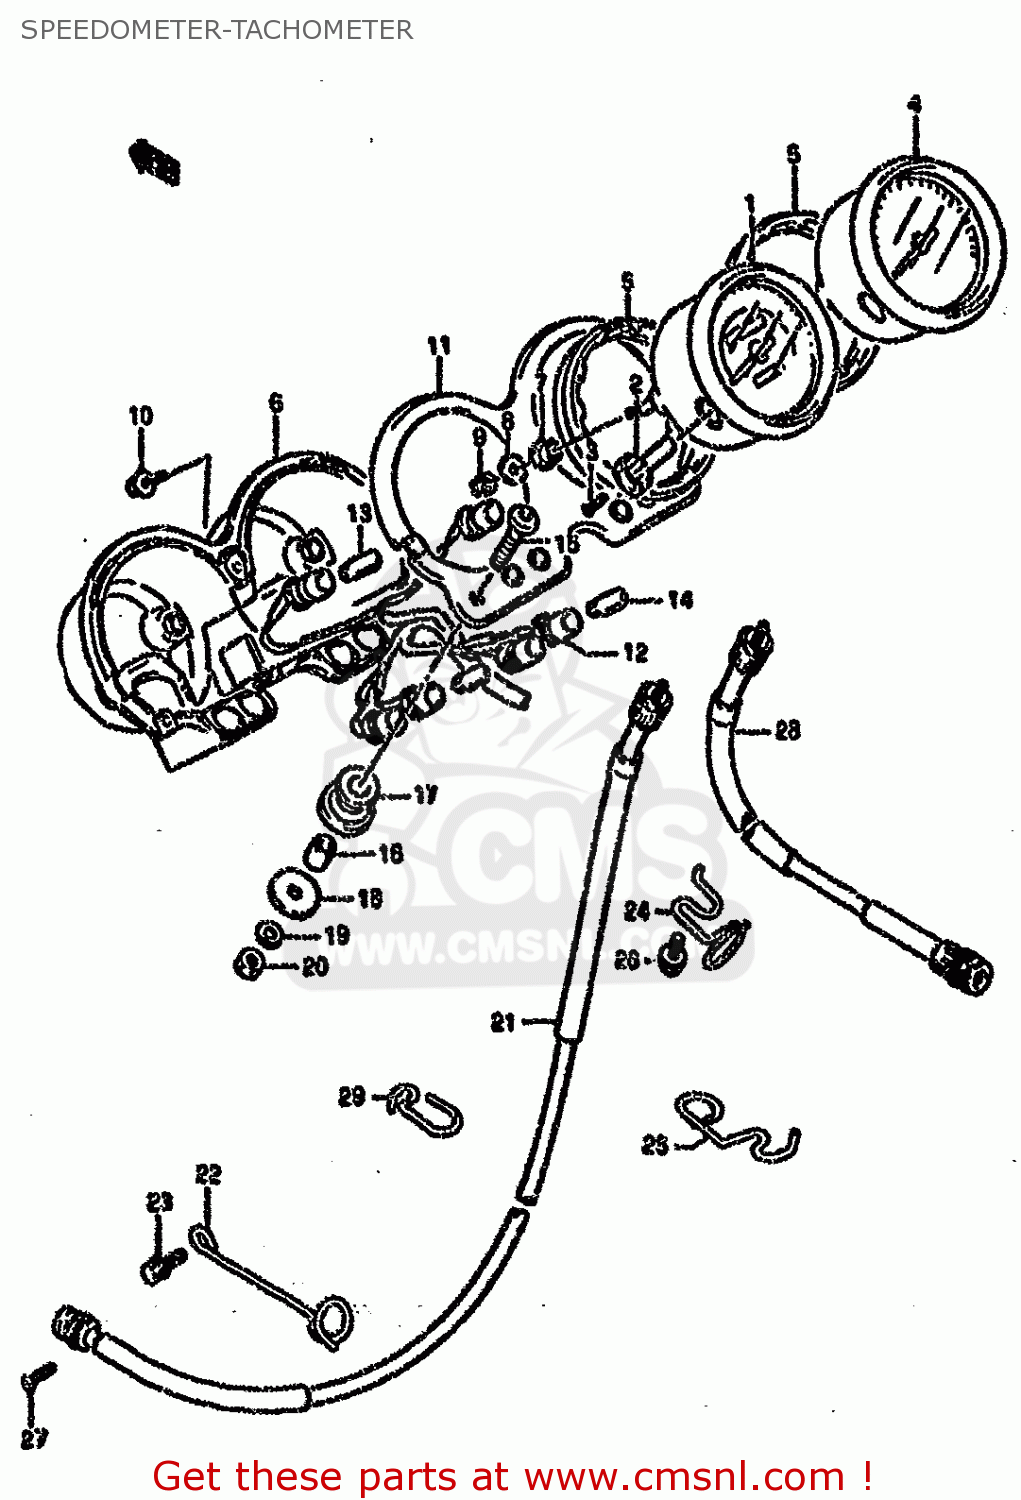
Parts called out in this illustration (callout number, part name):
1	SPEEDOMETER(MILE/KILO)
2	KNOB
3	SCREW(2X6)
4	TACHOMETER
5	DAMPER
6	COVER
7	CUSHION
8	WASHER,METER
9	NUT
10	SCREW
11	BRACKET,METER
12	SOCKET
13	BULB(12V3.4W,T10)
14	BULB(12V1.7W,T10,WB121)
15	BOLT(6X30)
16	SPACER (6.1X10X15.7)
17	CUSHION,METER BRACKET
18	WASHER (6.5X29X1.6)
19	WASHER,LOCK
20	NUT
21	CABLE ASSY,SPEEDOMETER
22	CLAMP,SPEEDOMETER CABLE
23	BOLT
24	GUIDE,SPEEDOMETER CABLE
25	GUIDE,SPEEDOMETER CABLE NO.2
26	BOLT
27	SCREW
28	CABLE ASSY,TACHOMETER
29	GUIDE,SPEEDOMETER CABLE NO.3
